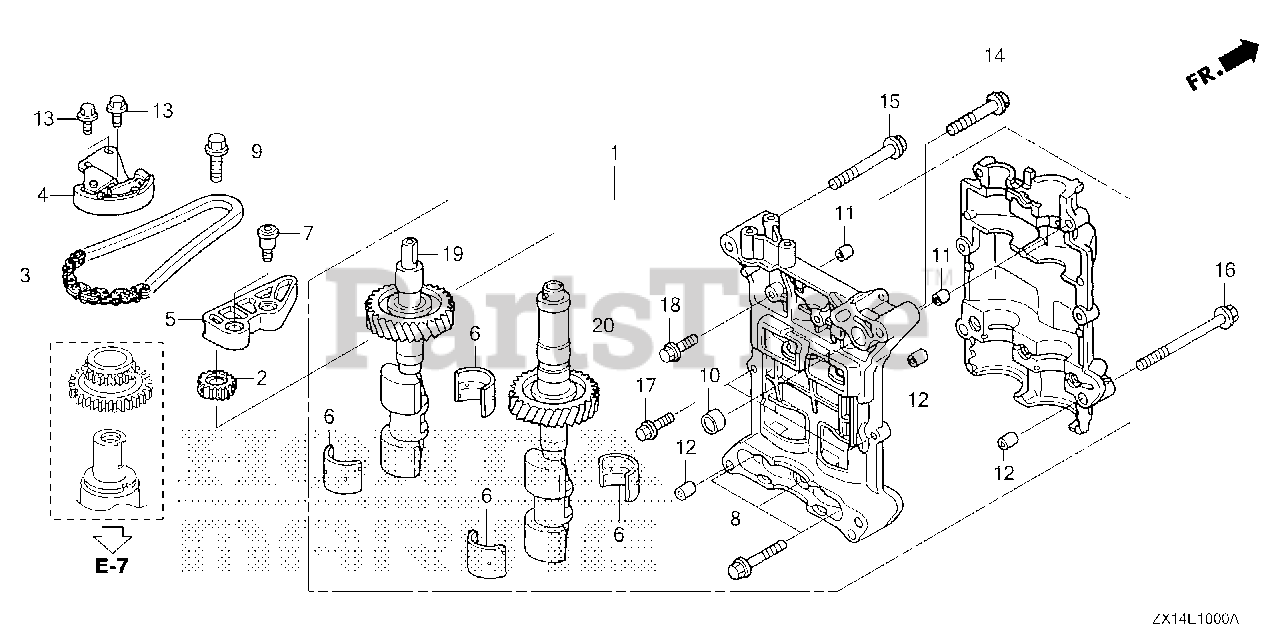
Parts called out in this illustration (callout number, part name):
1	CASE ASSY., BALANCER HOLDER
2	SPROCKET, DRIVEN (17T)
3	CHAIN (62L)
4	TENSIONER, BALANCER SHAFT CHAIN
5	GUIDE, BALANCER SHAFT CHAIN
6	METAL, BALANCER SHAFT (DAIDO)
7	BOLT, CHAIN GUIDE
8	BOLT, FLANGE (8X55)
9	BOLT-WASHER (10X30)
10	PIN, DOWEL (18X13)
11	PIN A, DOWEL (8X10)
12	PIN A, DOWEL (12X16)
13	BOLT, FLANGE (6X14)
14	BOLT, FLANGE (8X50)
15	BOLT, FLANGE (8X75)
16	BOLT, FLANGE (10X105)
17	BOLT, FLANGE (6X25)
18	BOLT, FLANGE (6X32)
19	SHAFT, FR. BALANCER
20	SHAFT, RR. BALANCER
